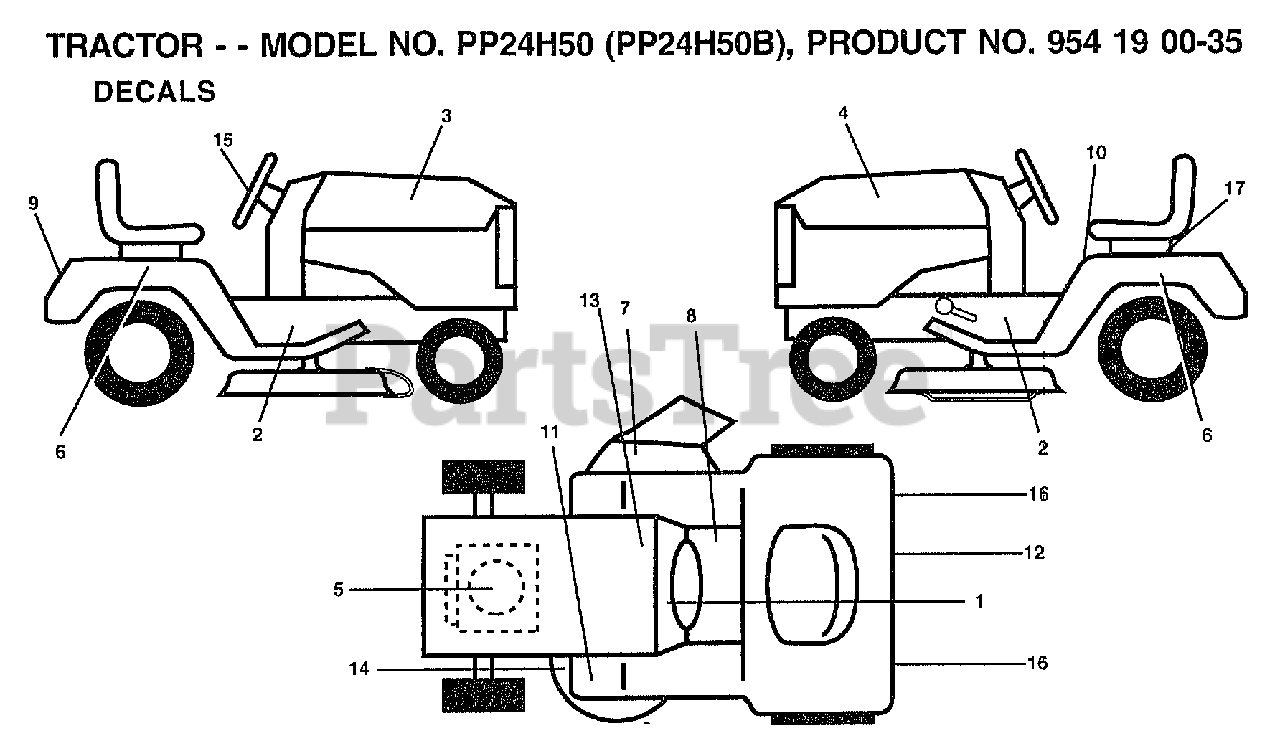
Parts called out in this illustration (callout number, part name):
1	DECAL OPER INSTR.
2	"DECAL.CHASSIS.50"""
3	DECAL.HOOD.RH
4	DECAL.HD.LH
6	DECAL.FENDR.AUTO
7	"DECAL, WARNING"
8	DECAL BRAK PARK
9	DECAL.FENDER.BELT.GUARD
10	DECAL.CAUT.ENG/FR
11	DECAL T
12	DECAL D-BAR CNTRL
13	DECAL.BATRY.3-3908
15	DECAL INS STRG WH
16	REFLECTOR-TAIL YT
17	RETAINER-SPRING
